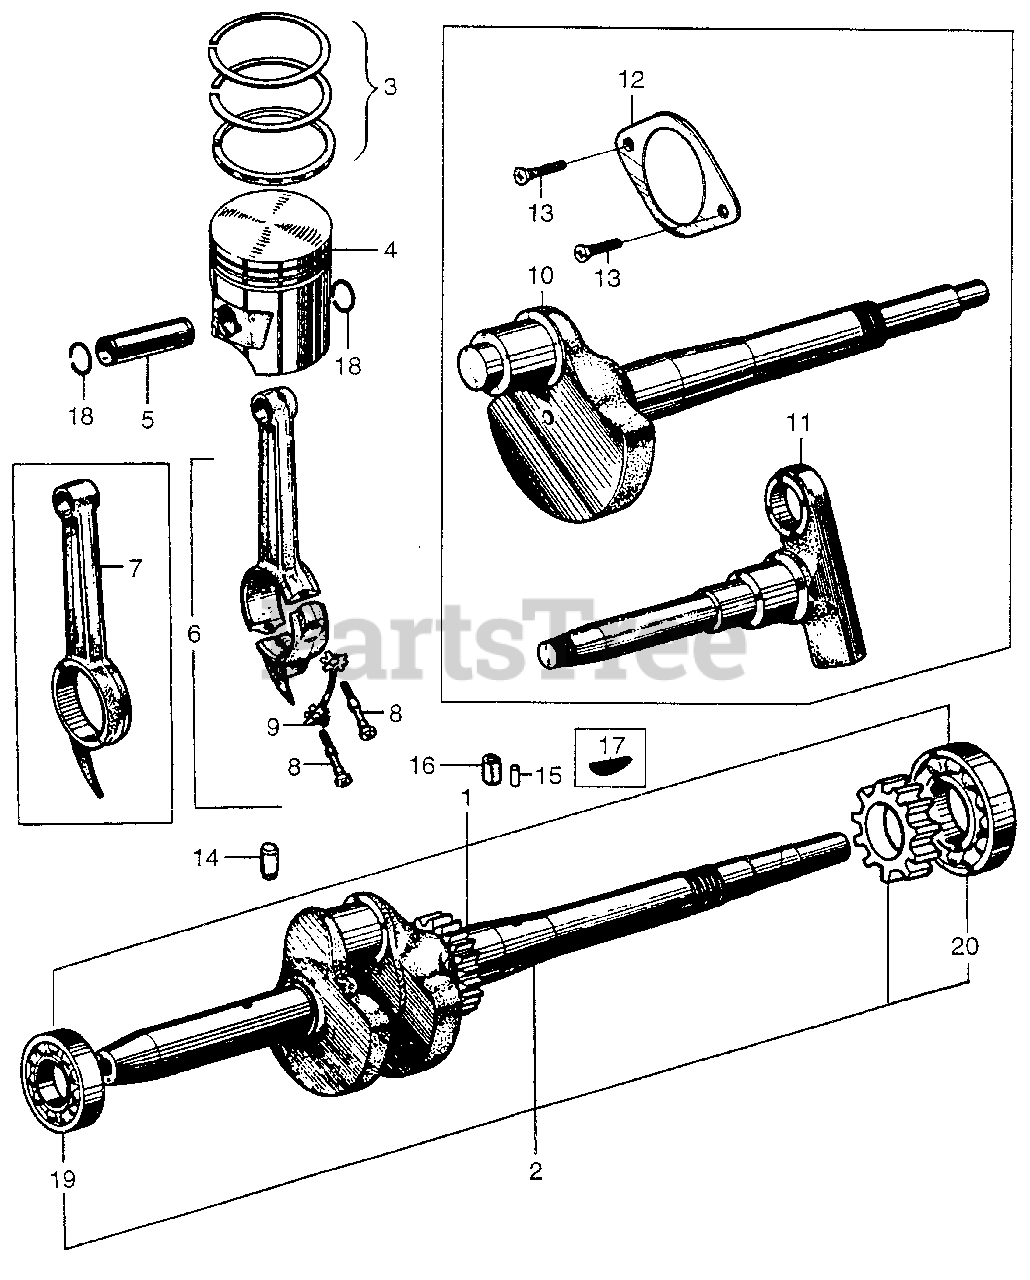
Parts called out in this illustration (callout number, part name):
1	CRANKSHAFT ASSY.
3	RING SET, PISTON (STD)
3	RING SET, PISTON (OS 0.25)
3	RING SET, PISTON (OS 0.50)
3	RING SET, PISTON (0.75)
4	PISTON (STD) (NOT AVAILABLE)
4	PISTON (OS 0.25)
4	PISTON (OS 0.50)
4	PISTON (0.75)
5	PIN, PISTON
6	ROD, CONNECTING
7	ROD, CONNECTING
8	BOLT, CONNECTING ROD
9	PLATE, LOCK (NOT AVAILABLE)
10	CRANKSHAFT, L.
11	CRANKSHAFT, R.
12	COVER, BEARING
13	SCREW, FLAT (5X12) (NOT AVAILABLE)
17	KEY, SPECIAL WOODRUFF (25X18)
18	CLIP, PISTON PIN (13MM)
19	BEARING, RADIAL BALL (6002)
20	BEARING, RADIAL BALL (6204)
